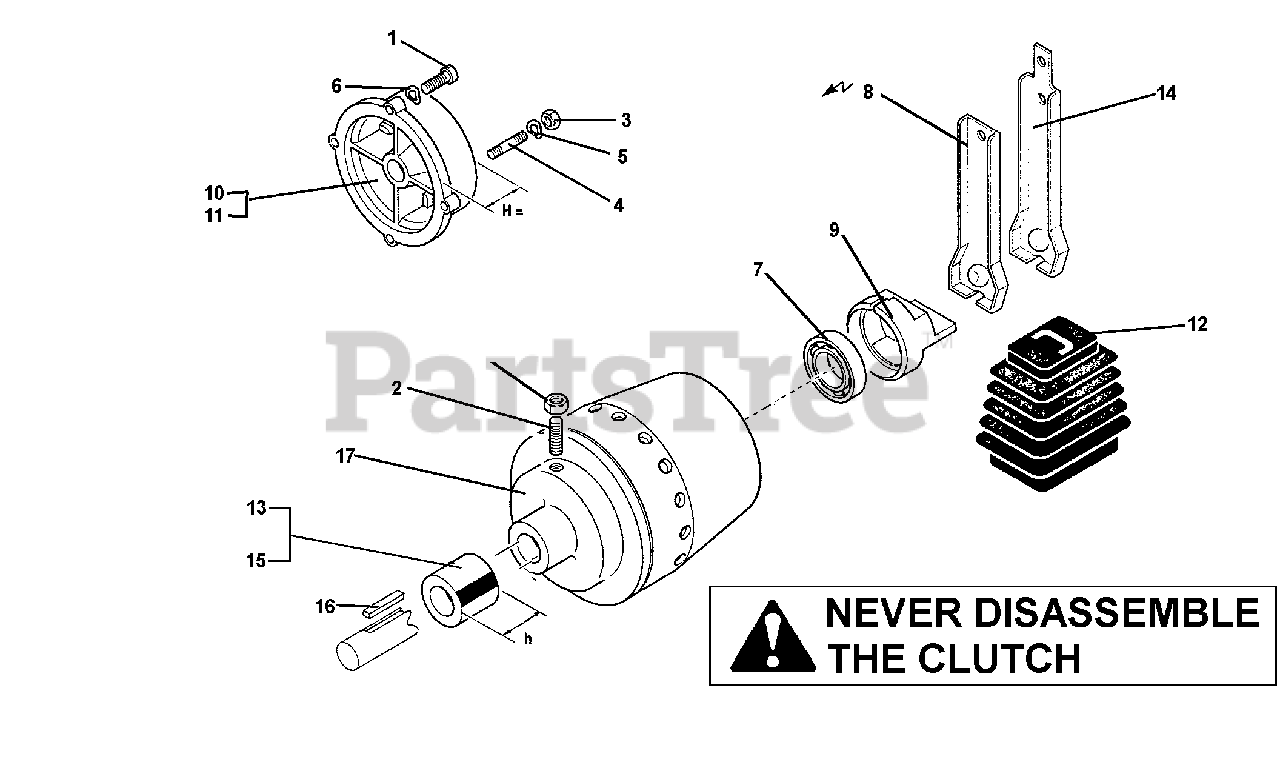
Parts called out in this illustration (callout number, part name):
1	SCREW 3/8X1"
2	SCREW M8X30
4	STUD,M8X40X14X14
5	WASHER, WAVE
6	WASHER, WAVE
7	BEARING,M17X40X12
8	CLUTCH LEVER, ELECTRIC START
9	CONE PUSHER
10	FLANGE, 52MM WIDE
11	FLANGE, 46MM WIDE
13	SPACER, 5MM WIDE
14	LEVER, RECOIL START
15	SPACER, 11MM WIDE
17	CLUTCH, 7HP & 8HP
